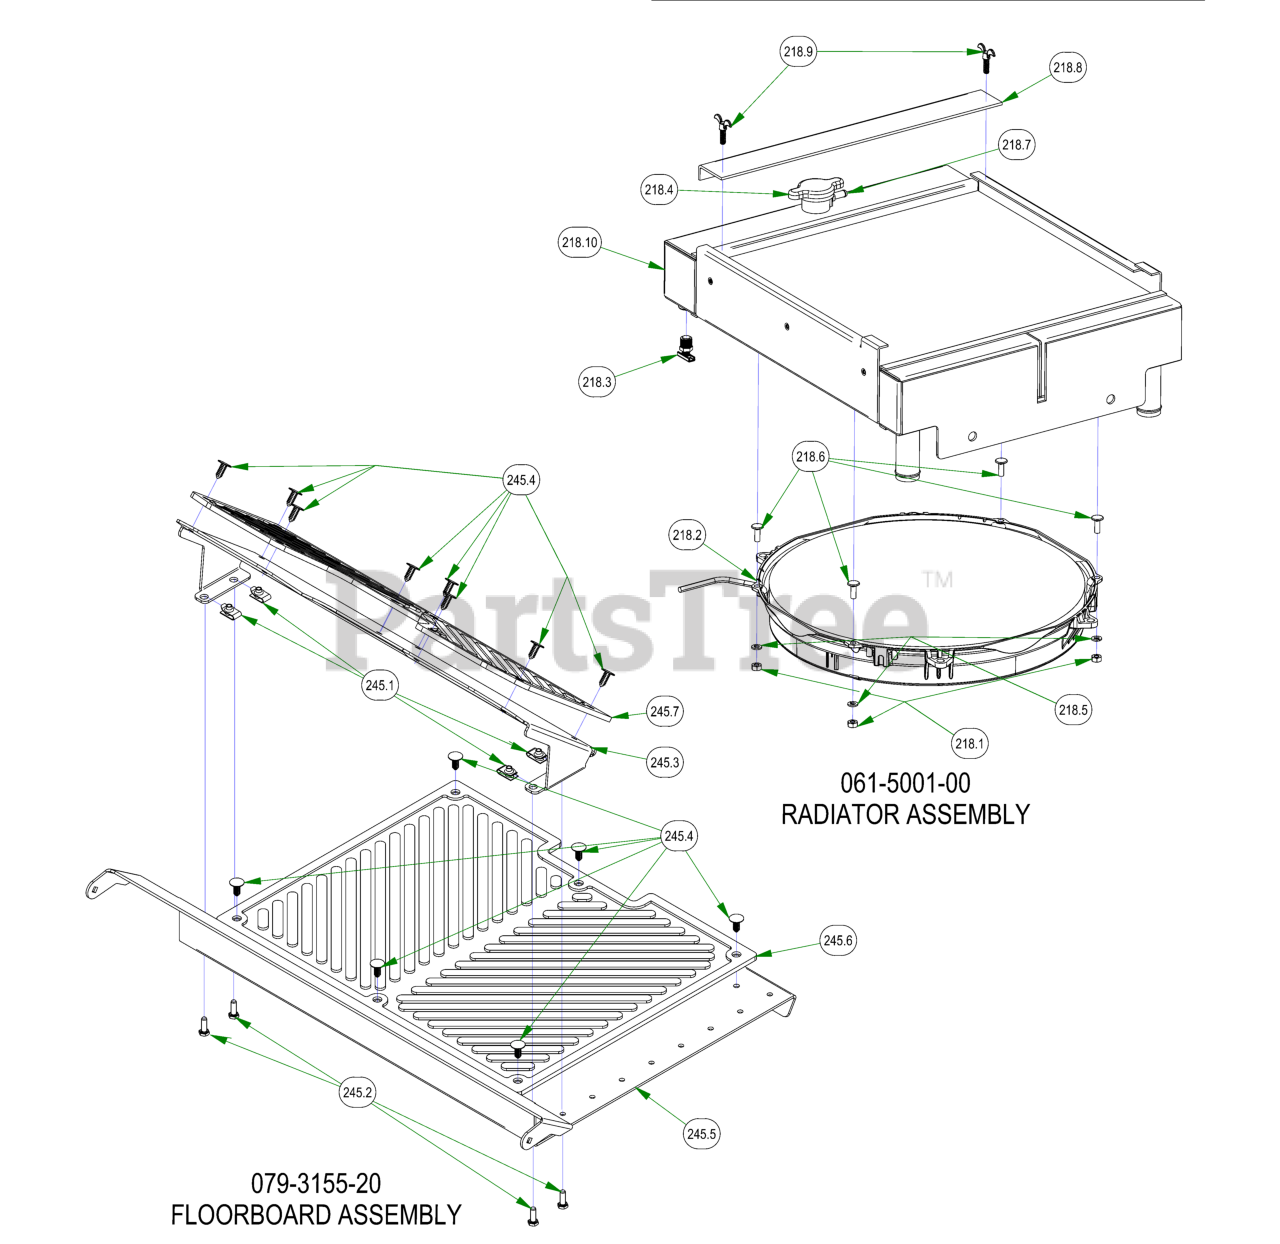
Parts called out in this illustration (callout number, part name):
218	2019 Diesel Radiator Kit
218.1	1/4-20 Hex Nut
218.2	Electric Fan for 2019 Diesel Radiator
218.3	1/4 NPT Drain Plug
218.4	radiator cap
218.5	1/4" Lock Washer
218.6	1/4" x 3/4" Carriage Bolt
218.7	1/4 Barb to 3/16 NPT Overflow Fitting
218.8	Screen Rentention Plate for 2019 Diesel Radiator
218.9	1/4-20 x 3/4 Thumb Screw
218.10	2019 Diesel Radiator
245	R-Series Floorboard Assembly
245.1	1/4-20 Cage Nut
245.2	1/4-20 X 3/4 HEX CAP SCREW (GR.5) ZINC
245.3	OUTLAW ADJUSTABLE FOOT PLATE-ORANGE
245.4	Ratchet Fastener
245.5	2019 Outlaw Floorboard
245.6	MAT (FLOOR)
245.7	MAT (FOOT PLATE)
